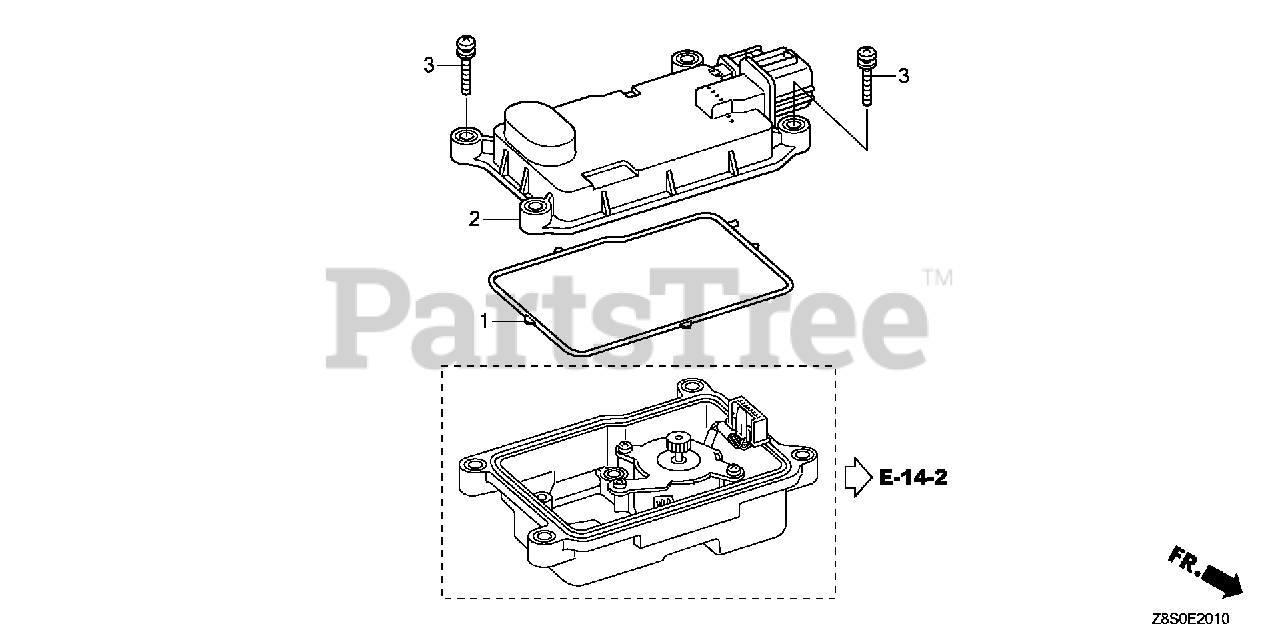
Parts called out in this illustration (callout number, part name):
1	SEAL, ELECTRONIC CONTROL UNIT COVER
2	CONTROL UNIT, ELECTRONIC
3	SCREW-WASHER (4X20)
